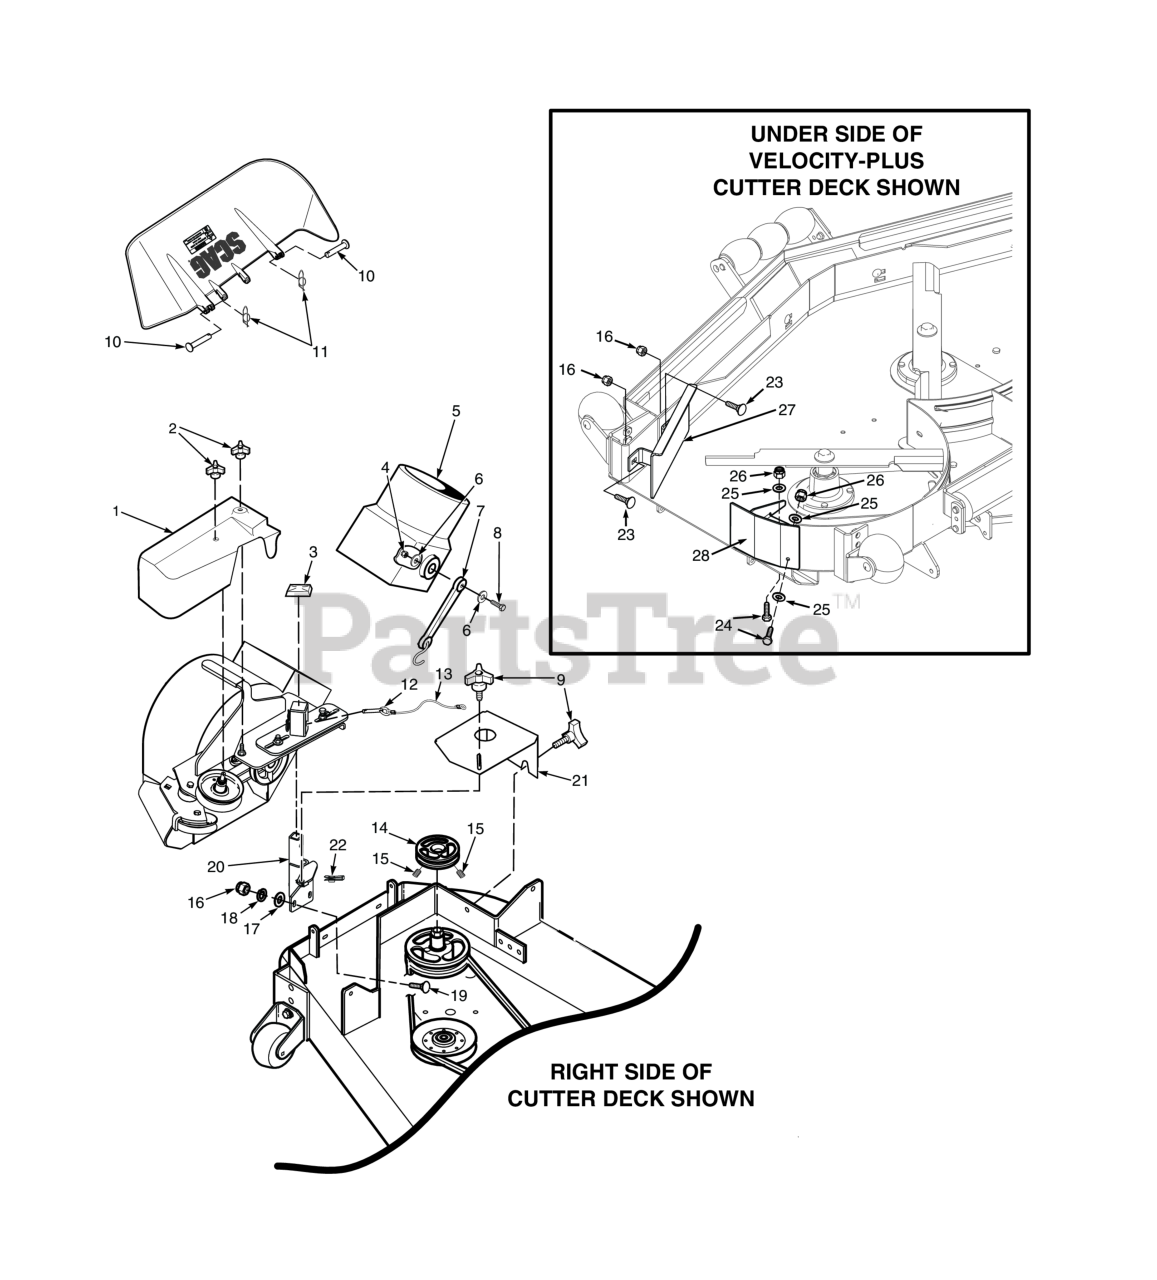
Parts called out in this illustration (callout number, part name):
1	Belt Cover, GC-STT - 61"
2	Wing Nut, 3/8-16 (Small) Top side
3	Cap, Square Vinyl
4	HEX, NUT, ELASTIC STOP LOCK, 1/4-20
5	Adapter, Blower GC-STC,
6	Flatwasher, 1/4" (.312 x .750 x .065")
7	Rubber Strap 7-3/4"
8	SERR. FLG. HEX HEAD CAPSCREW, 5/16-18 X 3/4
9	Knob W/Stud, 3/8-16 x 1-1/4"
10	Clevis Pin, 5/16 x 1-1/2"
11	Pin, Rue Cotter 5/16 Dia.
12	Pin, Ring 1/2 x 2-1/4"
13	Lanyard, Deck Height Pin
14	Pulley, 5-1/2" Dia. - 1.125" Bore, (61")
15	Setscrew, Hex Socket Knurl Cup Pt. 5/16 - 18 (nylock)
16	HEX NUT, ELASTIC STOP LOCK, 3/8-16
17	Lockwasher, 3/8" Spring, Kawasaki FX / FT & FT-EFI / B&S 32BV
18	Flatwasher, 3/8" Special (.391 x .938 x .105)
19	SHORT SQ. NECK CARRIAGE BOLT, 3/8-16 X 1-1/4"
20	Mounting Post Weldment, Blower, (61")
21	Belt Cover Assembly, GC-STT-61V w/Cap
22	U-Nut, 3/8-16 (short)
23	Carriage Bolt, 3/8-16 x 1.0"
24	Bolt, Heax Head 5/16-18 x 1" (48V / 52V)
25	Flatwasher, 5/16-.375 x .875 x .083 (35BV & 37BV-EFI)
26	HEX NUT, ELASTIC STOP LOCK, 5/16-18
27	Baffle Weldment - 61" Deck
28	Baffle, Turbo - 61" Deck
